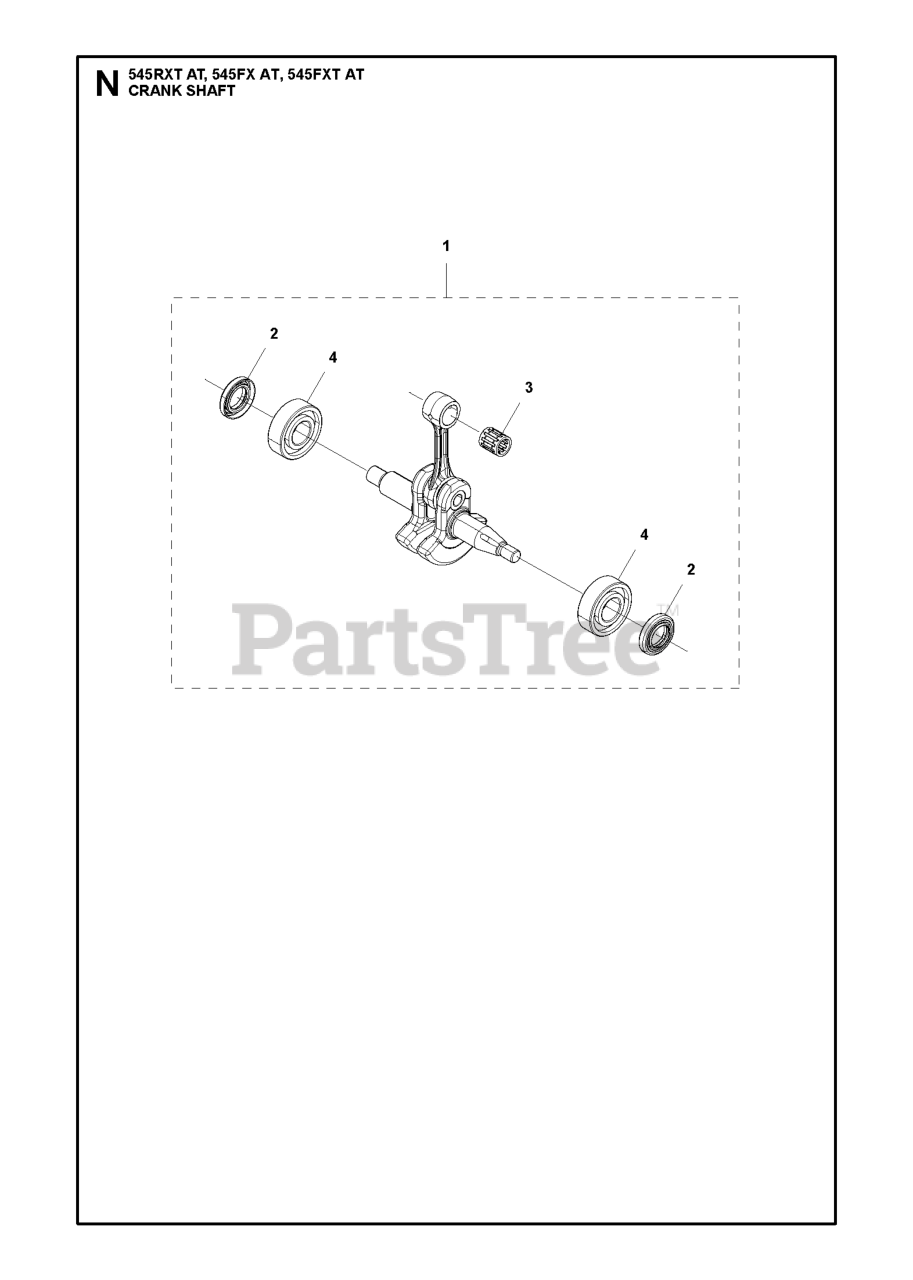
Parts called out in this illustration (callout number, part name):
1	CRANKSHAFT KIT SPARE PART 545
2	RADIAL SEAL 15X26X5,3
3	NEEDLE BEARING
4	BALL BEARING
